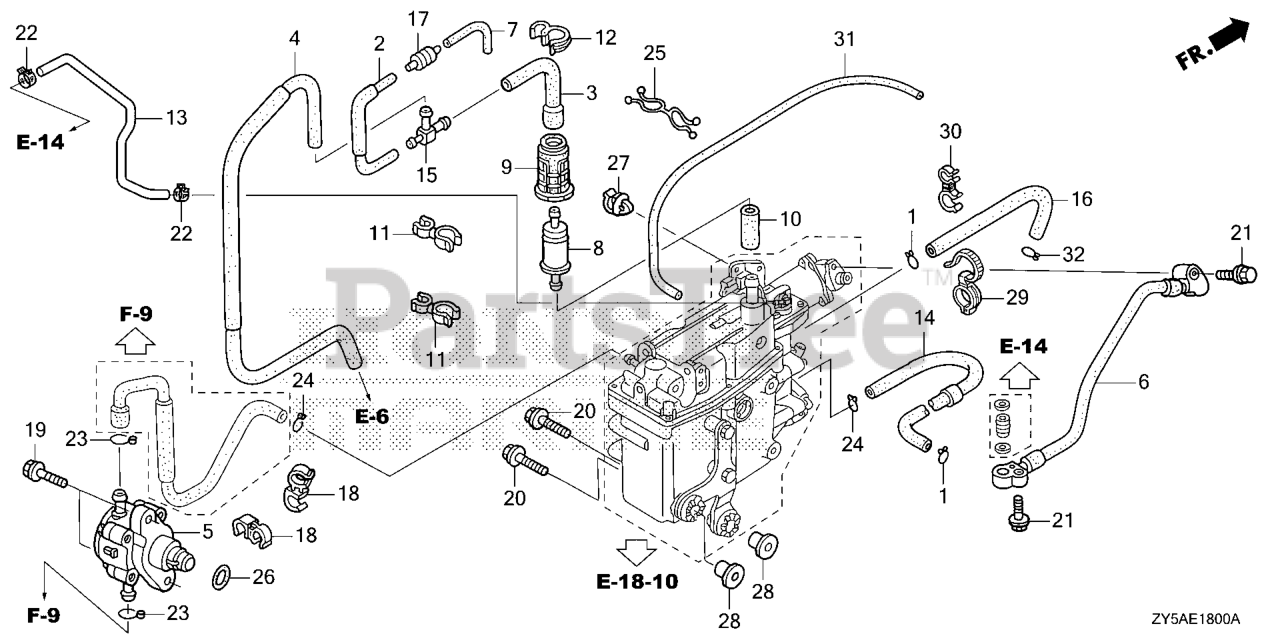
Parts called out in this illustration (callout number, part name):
1	CLIP, TUBE (ENGINE NO.)
2	TUBE C, AIR VENT
3	TUBE B, AIR VENT
4	TUBE, AIR VENT
5	PUMP ASSY., FUEL (MSDS)
6	HOSE, FUEL
7	TUBE D, FUEL
8	FILTER, FUEL PUMP
9	SUSPENSION, STRAINER
10	TUBE B, FUEL
11	CLAMP, HOSE
12	CLAMP, PIPE
13	HOSE, PRESSURE REGULATOR RETURN
14	TUBE F, WATER
16	TUBE G, WATER
17	VALVE, CHECK
18	CLIP, SENSOR HOSE
19	BOLT, FLANGE (6X27)
20	BOLT-WASHER (8X35)
21	BOLT, FLANGE (6X25)
22	CLAMP, TUBE (D10.7)
23	CLIP, TUBE (B1 14.5)
24	CLIP, TUBE (B12)
25	CLIP, FUEL HOSE
26	O-RING (33.2X2.4) (NOK)
27	CLIP, HARNESS
28	COLLAR (8.5X14.5)
29	CLIP, TUBE (135MM) (BLACK)
30	CLAMP, PURGE HOSE (NOT AVAILABLE)
31	BULK HOSE, FUEL (3.5X3000) (3.5X120)
32	CLIP, TUBE (B1 11)
